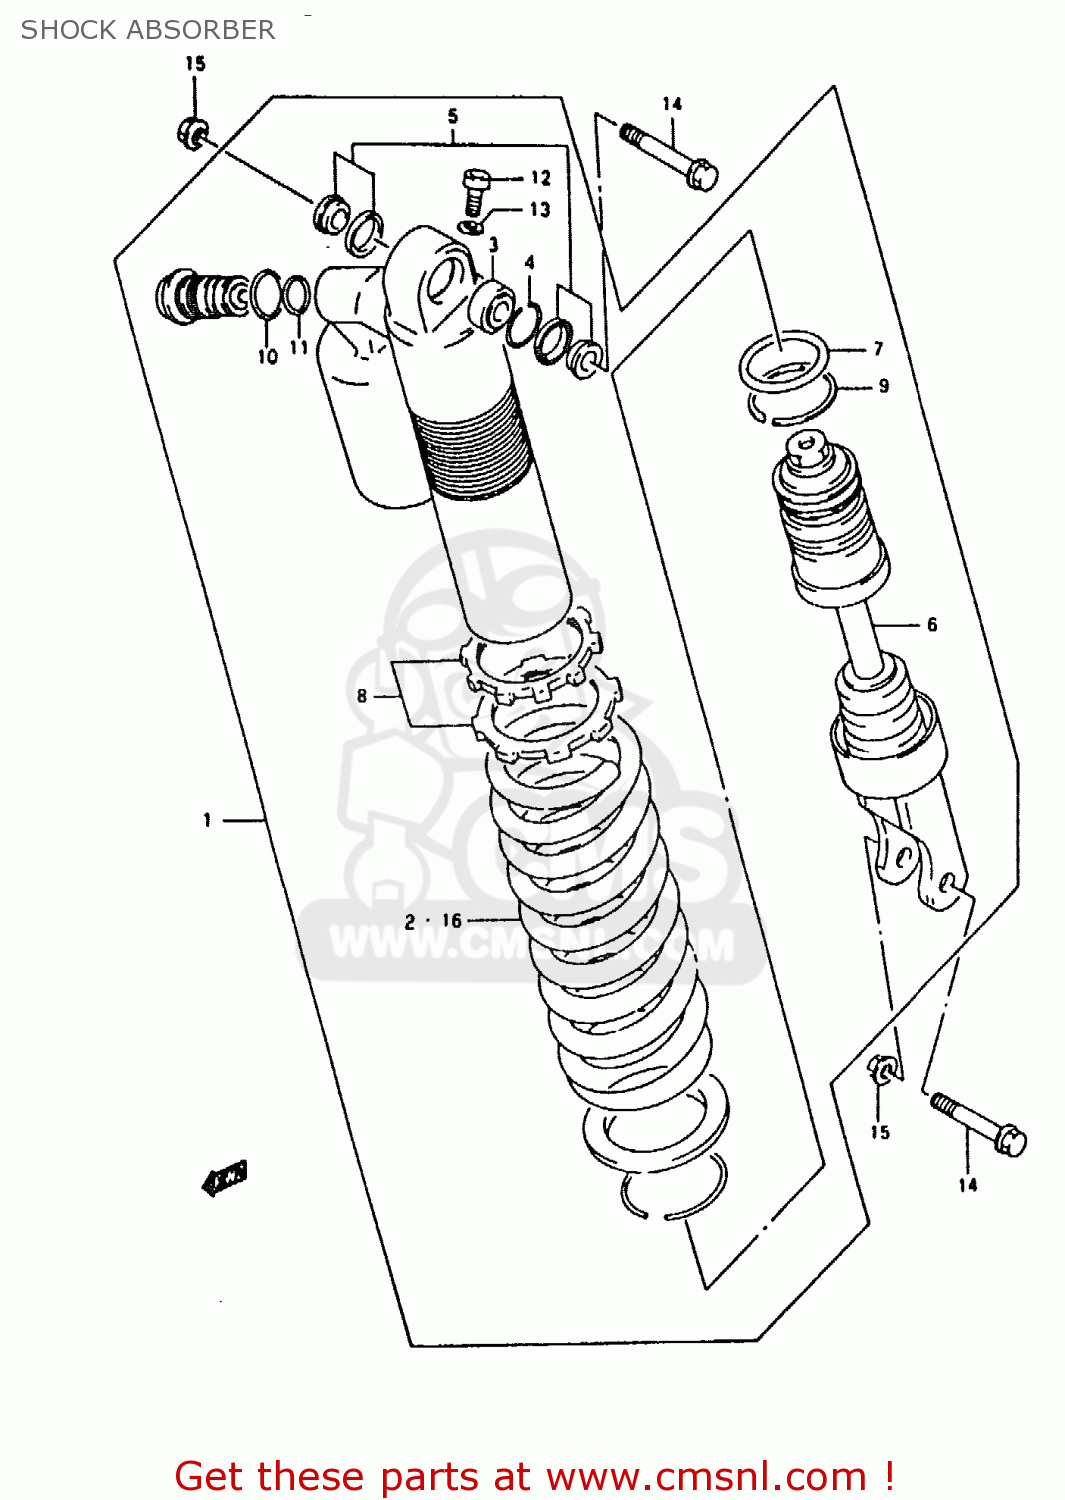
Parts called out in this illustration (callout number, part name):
1	ABSORBER ASSEMBLY,REAR SHOCK
2	SPRING(K:5.2)
3	BEARING,RR CUSHION LEVER RR
4	RING,STOPPER
5	COLLAR SET,RR SHOCK ABSORBER
6	ROD,PISTON
7	O RING
8	ADJUSTER SET,SHOCK ABSORBER
9	RING,STOPPER
10	O RING
11	O-RING,FORK BOLT,LOWER
12	BOLT
13	GASKET,DRAIN,PLUG (NAS)
14	BOLT,REAR SHOCK ABSORBER
15	NUT
16	SPRING,REAR (K=5.4)
